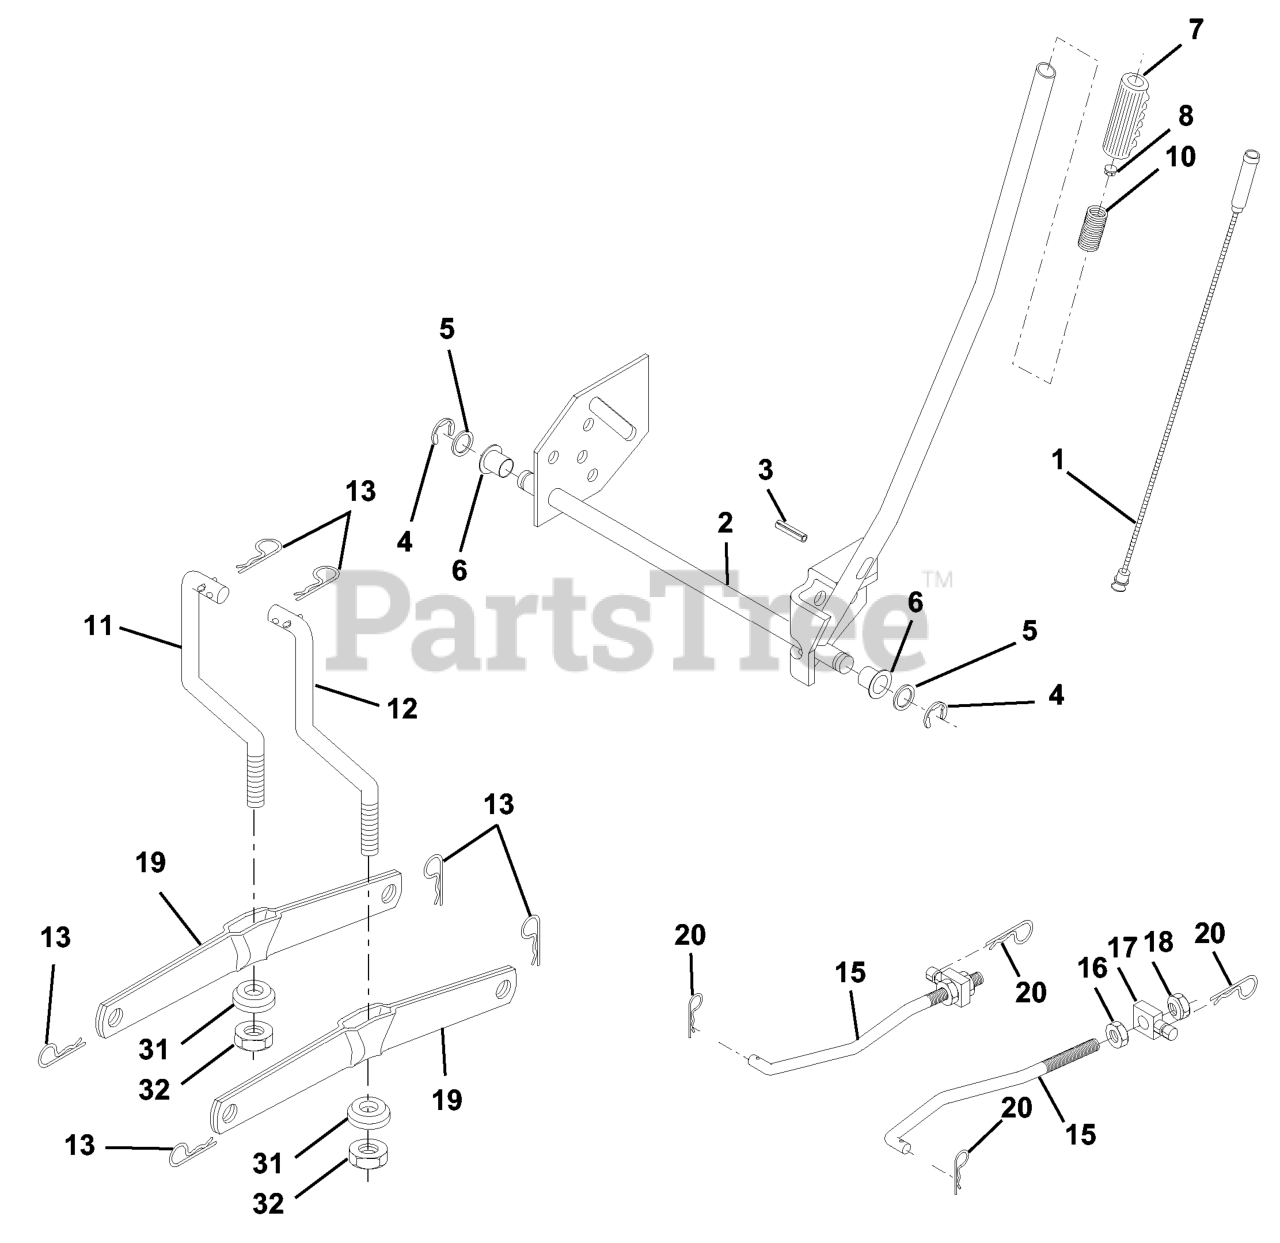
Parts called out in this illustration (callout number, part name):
1	WIRE.INNER.HANDLE.LIFT.LEVER
2	SHAFT ARM LIFT RH
3	PIN GROOVE.
4	RETAINING RING LT
6	BEARING.NYLON
8	PLUNGER BUT KIT
10	SPRING, COMP T
11	LINK LIFT LH
12	LINK LIFT RH
13	RETAINER-SPRNG RB
15	FRONT LINK
16	NUT.HEX.JAM.1/2-13
17	TRUNION
18	NUT.LK.W/WSH.1/2.
19	ARM.REAR.SUSPENSION
20	SPRING RETAINER
31	BEARING PIVOT
32	NUT CROWNLOCK 3/8-24
